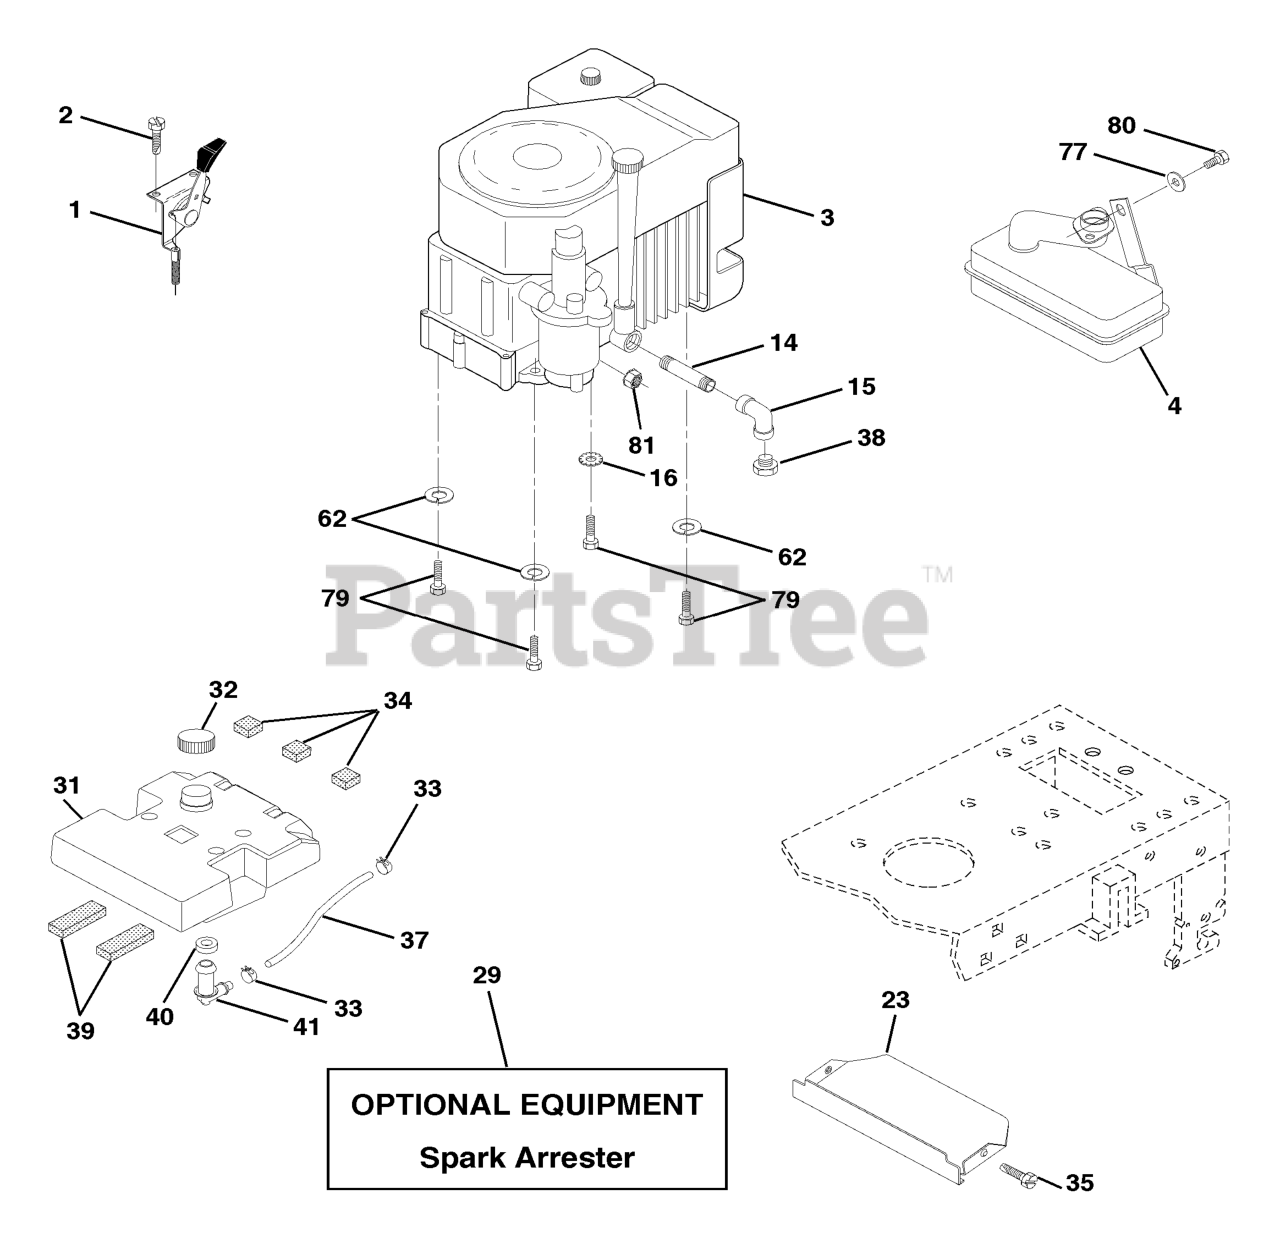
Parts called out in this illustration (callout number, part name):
1	CONTROL SWITCH 27 LH
2	SCREW LT
4	MUFFLER LT 12.5
14	Nipple Pipe 3/8 Npt X 3-1/2
15	ELBOW
16	WASHER EXT TOOTH LOCK 5/16
23	SHIELD HEAT
29	KIT.SPARK ARRESTOR 794945 B&S
31	TANK.FUEL(3.5.GAL)
32	FUEL CAP
33	HOSE CLAMP
34	PAD-SPACER LT
35	SCREW.THDROL.5/16-18X3/4.TTY
37	HOSE T
38	Plug Oil Drain
39	PAD IDLER TI
40	BUSHING OUTLET T
41	STEM FUEL TANK
62	WASHER.LOCK.HVY.HLCL.SPR.5/16
77	WASHER
79	BOLT, HEX
80	Bolt Hex Hd. 5/16-18 unc x 1/2
81	NUT FLANGE 1/4-20 STARTER NUT
